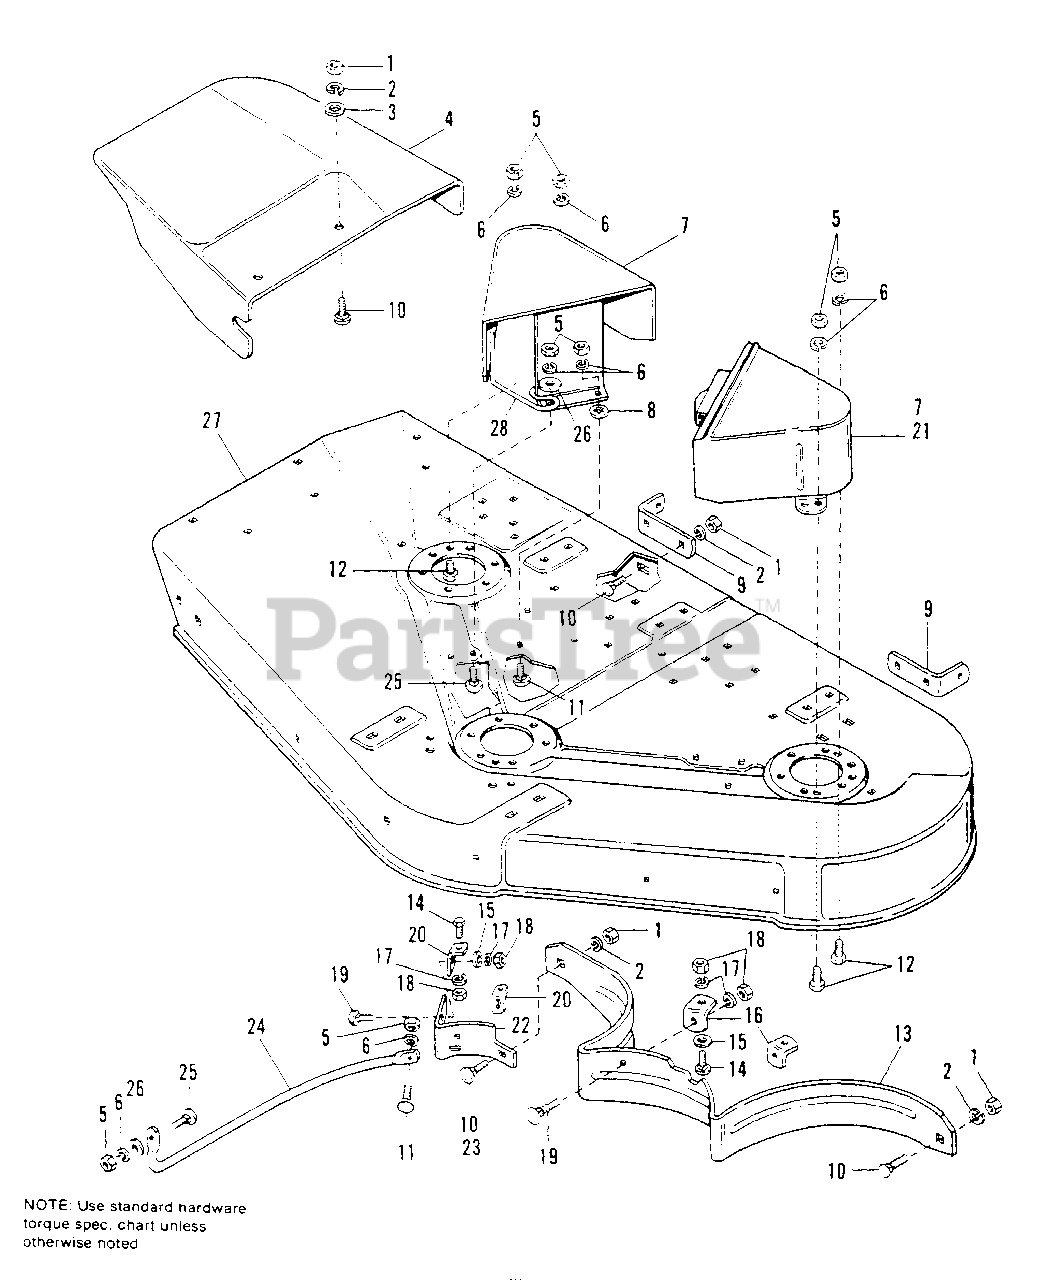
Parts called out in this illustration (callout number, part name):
1	NUT, Hex, 3/8-16 (Qty. 7 used on 48")
2	LOCKWASHER, 3/8 (Qty. 7 used on 48")
3	WASHER, Plain, 3/8
5	NUT, Hex, 5/16-18 (Qty. 6 used on 42")
6	LOCKWASHER, 5/16 (Qty. 6 used on 42")
7	ARBOR COVER ASSY. (Qty. 1 used on 42")
8	PUSHNUT, 5/16 (Qty. 2 used on 42")
9	BRACKET, Roller Support
10	BOLT, Carriage, 3/8-16 x 3/4 (Qty. 7 used on 48")
11	BOLT, Carriage, 5/16-18 x 3/4 (Qty. 2 used on 42")
12	CAPSCREW, Hex, 5/16-18 x 1
13	BAFFLE-42"
14	CAPSCREW, Hex, 1/4-20 x 3/4
15	WASHER, 1/4
16	CLIP, Baffle
17	LOCKWASHER, 1/4
18	NUT, Hex, 1/4-20
19	BOLT, Carriage, 1/4-20 x 5/8
20	CLIP GUARD & BAFFLE
21	ARBOR COVER ASSY.-42"
22	BAFFLE, Discharge
23	BOLT, Carriage, 3/8-16 x 1.00 (48" only)
24	GUARD, Mower Discharge
25	BOLT, Carriage, 5/16-18 x 1
26	WASHER, 11/32 x 1
27	42" ROTARY MOWER HOUSING KIT (Incl. Safety Decals)
27	48" ROTARY MOWER HOUSING KIT (Incl. Safety Decals)
